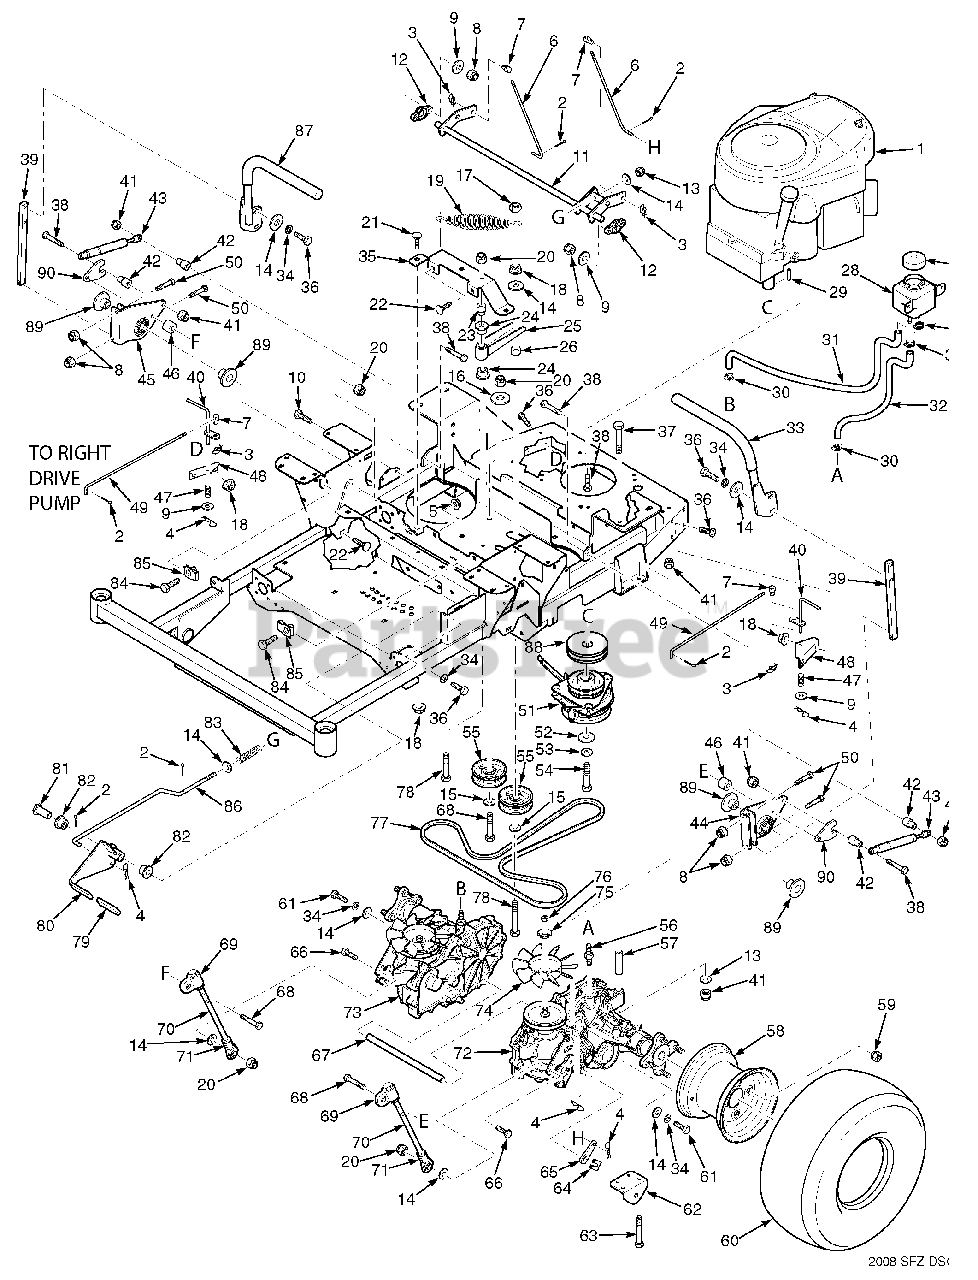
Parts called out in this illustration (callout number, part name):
1	Engine, Briggs & Stratton 26hp
2	Cotter Pin, 3/32 x 1"
3	Pin, Rue Cotter 3/8" Dia.
4	Hair Pin, .080 x 1.19"
5	Nut, Serrated Flange 5/16-18
6	Rod, Brake Adjustment
7	Joint, Swivel
8	Nut, Elastic Stop 1/4-20
9	Flatwasher, 1/4-.312 x .750 x .065
10	Bolt, Serrated Flange 1/4-20 x 1-1/4"
11	Weldment, Brake Lever
12	Bearing
13	Flatwasher, 5/16-.375 x .875 x .083
14	Flatwasher, 3/8-.391 x .938 x .105
15	Flatwasher, 3/8-.391 x .938 x .105 HD
16	Flatwasher, 3/8-.406 x 1.5 x 7 GA.
17	Nut, Center Lock 3/8-16
18	Nut, Serrated Flange 3/8-16
19	Spring, Transmission Idler
20	Nut, Elastic Stop 3/8-16
21	Bolt, Carriage 3/8-16 x 3/4"
22	Bolt, Carriage 5/16-18 x 3/4"
23	Shaft Pivot, Idler Arm
24	Bearing
25	Transmission Idler Arm Assembly
26	Spacer, Idler Pulley
28	Reservoir Assembly
29	Key, 1/4 x 1/4 x 1-3/4"
30	Clamp, 0.87" Max Dia.
31	Hose, RH Transmission
32	Hose, LH Transmission
33	Handle Bar Assembly, w/Grip
34	Lockwasher, 3/8" Spring
35	Support, Idler Arm
36	Bolt, Hex Head 3/8-16 x 1"
37	Bolt, Hex Head 5/16-18 x 5"
38	Bolt, Hex Head 5/16-18 x 1-1/2"
39	Bar, Control Lever
40	Dump Valve Lever
41	Nut, Elastic Stop 5/16-18
42	Spacer, Pump Dampener
43	Dampener
44	Control Link, LH
45	Control Link, RH
46	Spacer
47	Spring
48	Bracket, Dump Mounting
49	Linkage, Dump Valve
50	Bolt, Hex Head 1/4-20 x 1-1/2"
51	Electric Clutch Assembly (48, 52)
52	Flatwasher, 7/16-.469 x 1.75 x .25 (48, 52)
53	Lockwasher, 7/16" spring
54	Bolt, Hex Head 7/16-20 x 2-1/4" Patch
55	Pulley, 3-1/2" Dia.
56	Fitting, Transmission
57	Spacer, Axle
58	Rim w/Valve Stem (48, 52, 61)
59	Wheel Nut, 1/2-20
60	Wheel Assembly (48, 52)
61	Bolt, Hex Head 3/8-16 x 2-1/4"
62	Bracket, Pusharm Link
63	Bolt, Hex Head 5/16-18 x 3"
64	Clip, Brake Lever
65	Lever, Brake
66	Bolt, Hex Head 3/8-16 x 1-1/4"
67	Spacer, Axle
68	Bolt, Hex Head 3/8-16 x 2"
69	Rod End, Adjustable
70	Linkage, Pump
71	Stake, Rod End Assembly
72	Transaxle Assy., (ZL-KCEF-3LKG-1EXX)
73	Transaxle Assy., (ZL-GCEF-3LKF-1EXX)
74	Fan
75	Fan Washer
76	Fan Nut
77	Belt, TRansmission Drive
78	Bolt, Hex Head 3/8-16 x 3"
79	Grip, Brake Handle
80	Brake Handle Assembly
81	Spacer, Brake Handle
82	Bearing
83	Spring, Brake
84	Bolt, Hex Head 3/8-16 x 1-1/4" Special Lock
85	U-Nut, 3/8-16
86	Rod, Brake Linkage
87	Handle Bar w/Grip
88	Pulley, 4-1/2" Dia. 1" Bore
89	Spacer, Linkage
90	Nut, Control Linkage
